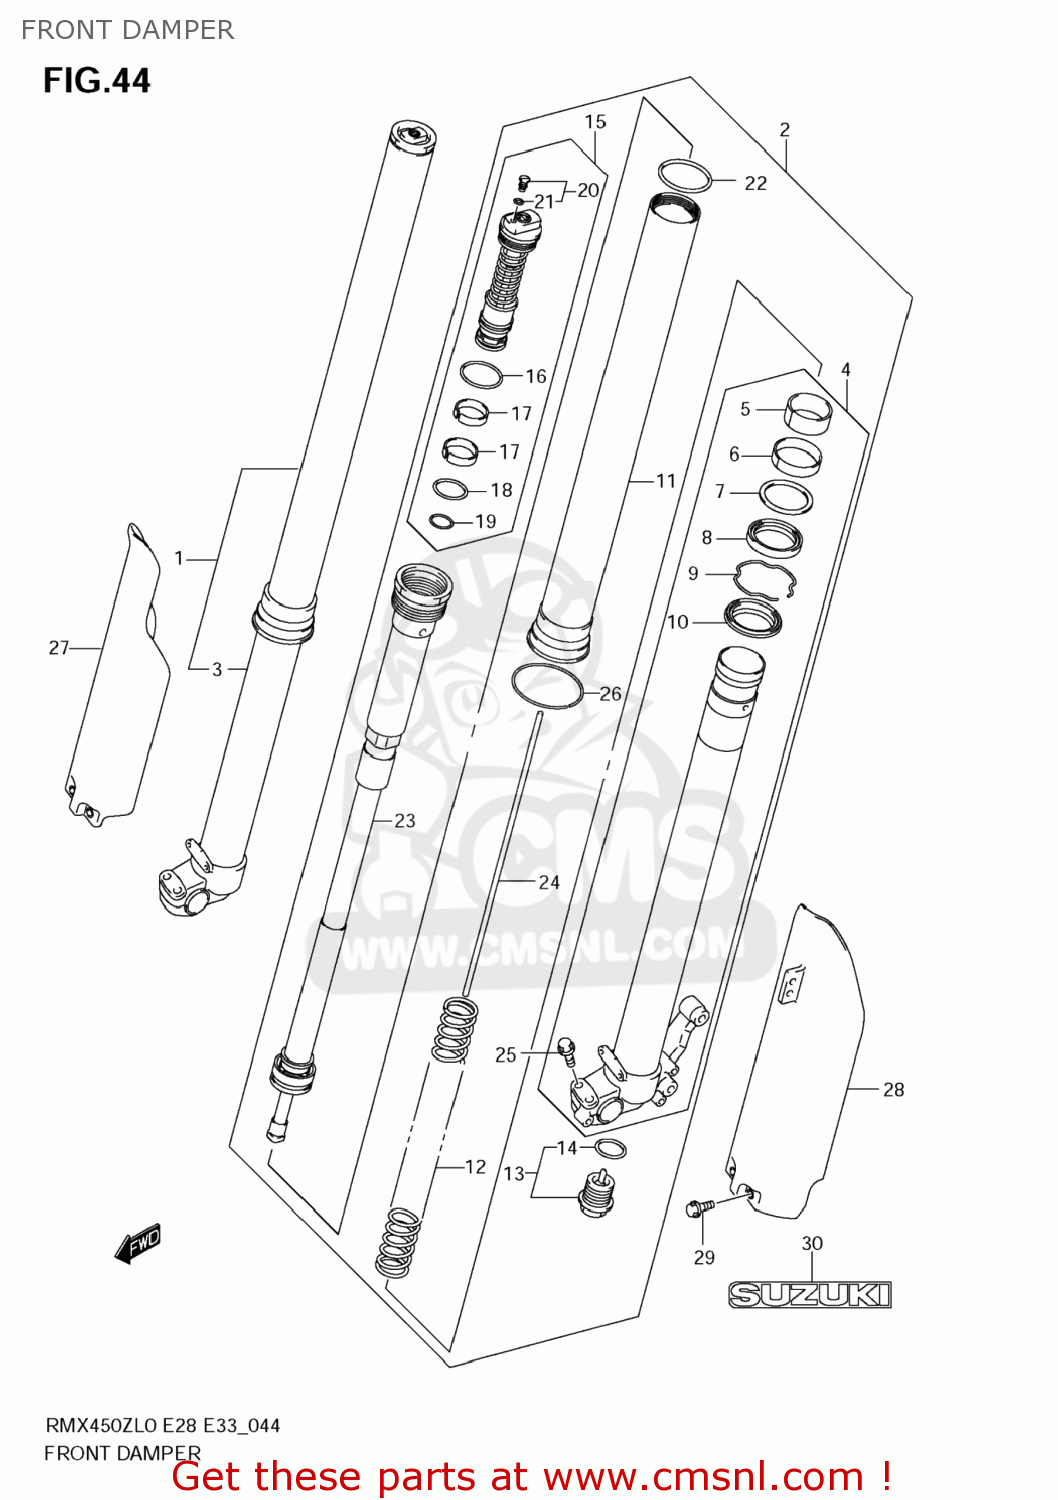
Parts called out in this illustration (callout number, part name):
1	DAMPER ASSY,FR FORK,R
2	DAMPER ASSY,FR FORK,L
3	TUBE,INNER,R
4	TUBE,INNER,L
5	BUSH
6	BUSH,GUIDE
7	SPACER,SEAL
8	SEAL,OIL
9	RING,OIL SEAL STOPPER
10	SEAL,DUST
11	TUBE,OUTER
12	SPRING,FR(K=0.47)
13	BOLT,CTR
14	O RING
15	BOLT,FORK
16	O RING
17	BUSH
18	O RING
19	O RING
20	BOLT,PLUG
21	O RING,PLUG
22	O RING
23	ROD,DAMPER
24	ROD,PUSH
25	BOLT
26	STOPPER,RING
27	PROTECTOR,FR FORK,R
28	PROTECTOR,FR FORK,L
29	BOLT(6X10)
30	EMBLEM,SUZUKI
